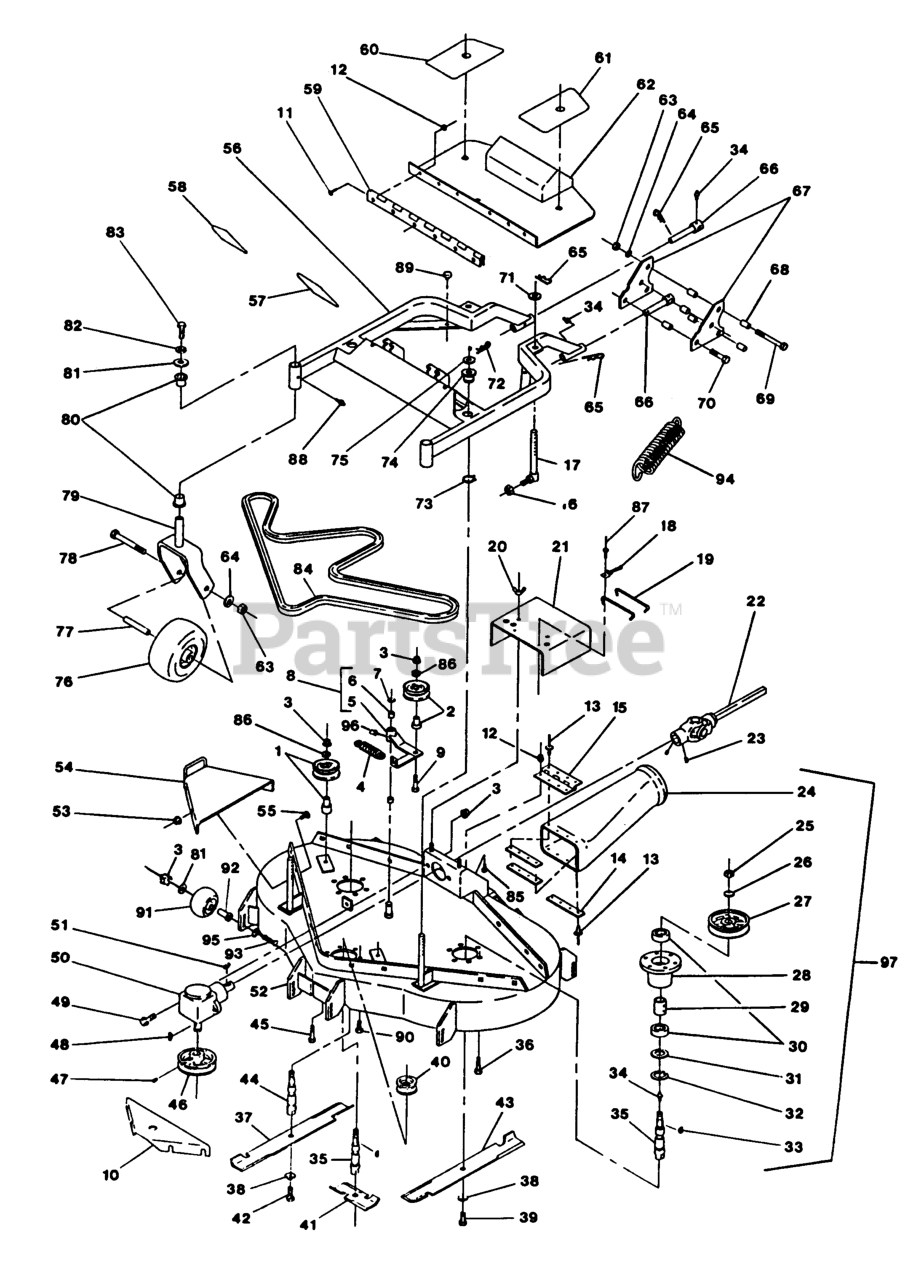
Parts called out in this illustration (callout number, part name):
1	KIT,IDLER & BUSHING
6	SLEEVE-BEARING
18	CLIP-DECK, HOLD UP ROD
20	WINGNUT-NYLOCK
22	PTO SHAFT,SHAFT HALF PNT
26	WASHER-SPRING
29	SPACER,BEARING
31	SEAL,MECHANICAL DUST
32	RING,SNAP WLDS N5000-244
36	SCRW,TPTTE HH
38	WASHER-SPRING
42	SCREW-CAP,HH
47	SCREW-SET
50	GEARBOX, PEERLESS
54	WLD,GUARD BELT
58	PAD,ANTI SKID UPPER RH
59	HINGE,FLOORPAN
60	PAD,ANTI SKID LOWER RH
65	PIN,HAIR COTTER
66	PIVOT - MOUNTING, W/ZERK
74	BUSHING-DECK
75	WASHER-FLAT
80	BEARING-FLANGED
84	BELT,DECK DRIVE
85	BOLT-CARR
87	Pop Rivet, Steel 3/16 X .250
91	ROLLER-SCALP, ANTI
92	BUSHING-ROLLER
97	CH-52REARDSCG-CENTER
